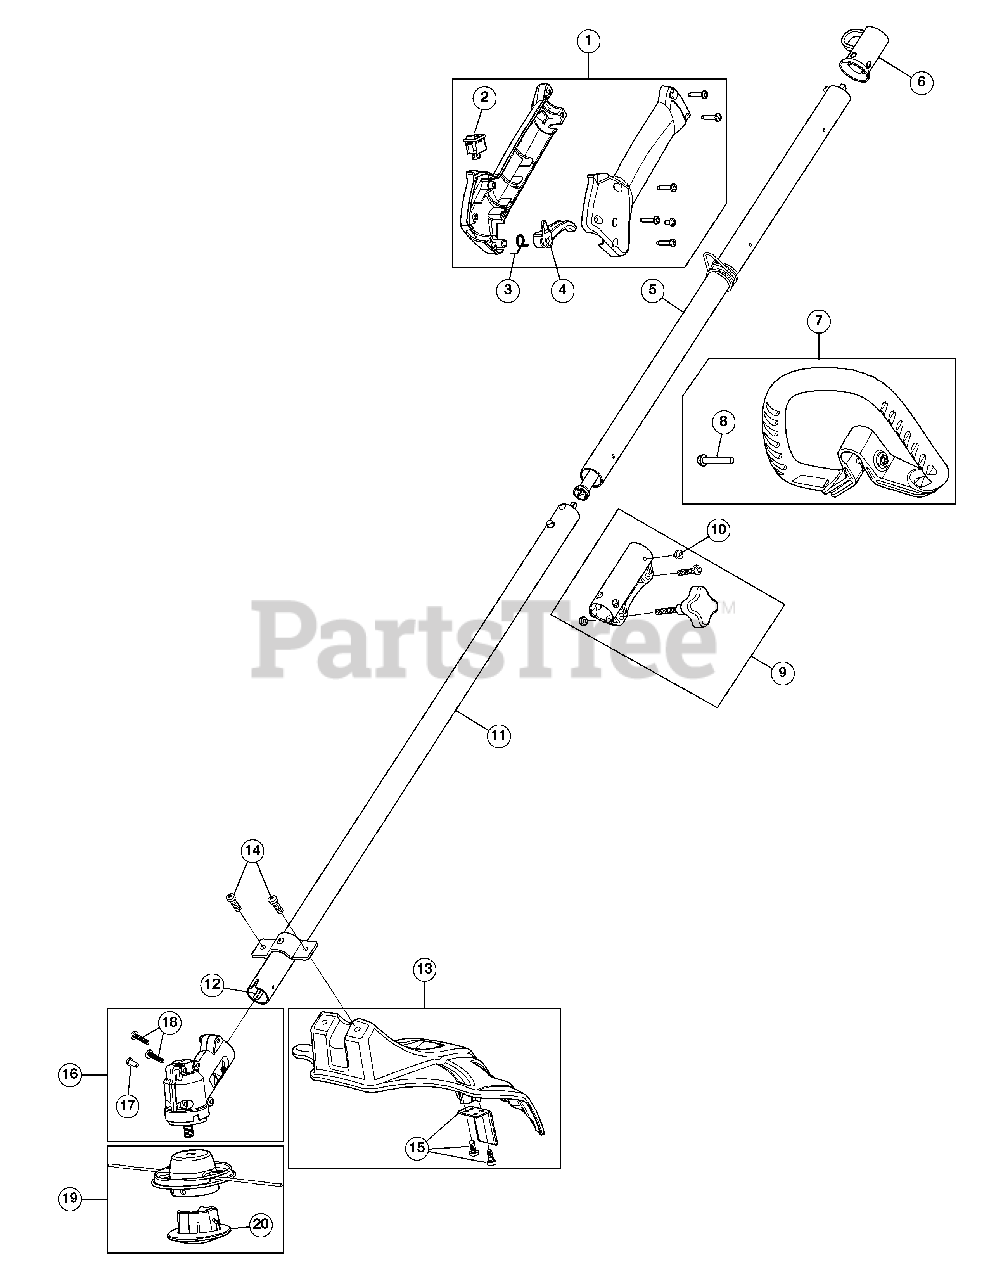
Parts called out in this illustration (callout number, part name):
1	Throttle Housing Assembly (Incl. 2 - 4)
2	Trigger Switch Assembly
3	Throttle Trigger Spring
4	Throttle Trigger
5	Upper Drive Shaft Assembly
6	Hanger
7	D-Handle Assembly (Incl. 8)
9	Split Boom Coupler (Incl. 10)
10	Coupler Anti-Rotation Screw
11	Lower Drive Shaft Housing (Incl. 12)
12	Lower Flexible Drive Shaft
13	Shield Assembly (Incl. 14 and 15)
14	Shield Mounting Screws
15	Blade Assembly
16	Gearbox Assembly (Incl. 17 and 18)
17	Gearbox Anti-Rotation Screw
18	Gearbox Mounting Hardware
19	Cutting Head Assembly (Incl. 20)
20	Cutting Head Cap
